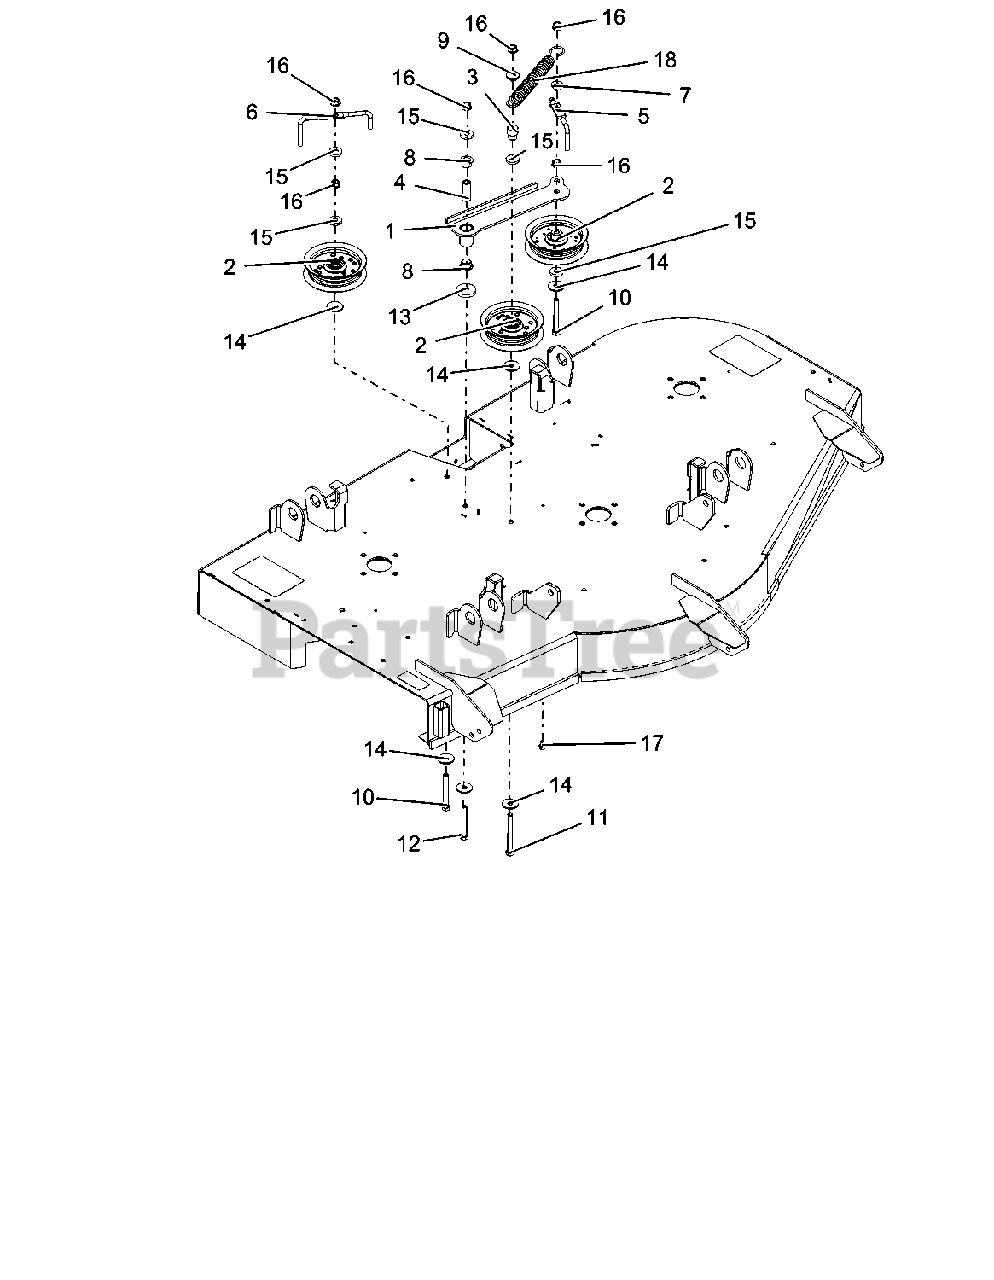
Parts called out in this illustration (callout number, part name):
1	WLDMT, IDLER - 52" IDLER ARM
2	ASM, IDLER 4"
3	BUSHING, IDLER
4	SPCR, .375IDX.625ODX1.66 PM
5	WIREFORM, BELT FINGER-RED
6	FINGER, BELT (RED)
7	BSHG, FLG .385 X .500 X .875 X .406
8	BSHG, FLANGE .625 x .75 x .50 x 1.00
9	BSHG-FLG .385X.500X.875X.31
10	BLT-HEX .38-16X3.00 GR5 FTH YWZC
11	BLT-HEX .38-16X3.50 GR5 YWZC
12	BLT-HEX .38-16X2.75 GR5 YWZC
13	WSHR-FL-STL .406X1.50X.245 YWZC
14	WSHR-FL-STL .406X1.25X.10 YWZC
15	WSHR-FL-STL .406X1.00X.188 YWZC
16	NUT, LK-TOP-FLG .38-16 YWZC
17	SCR-TAP .25-20X.50 HWH TR YWZ
18	SPRG, EXTENSION
